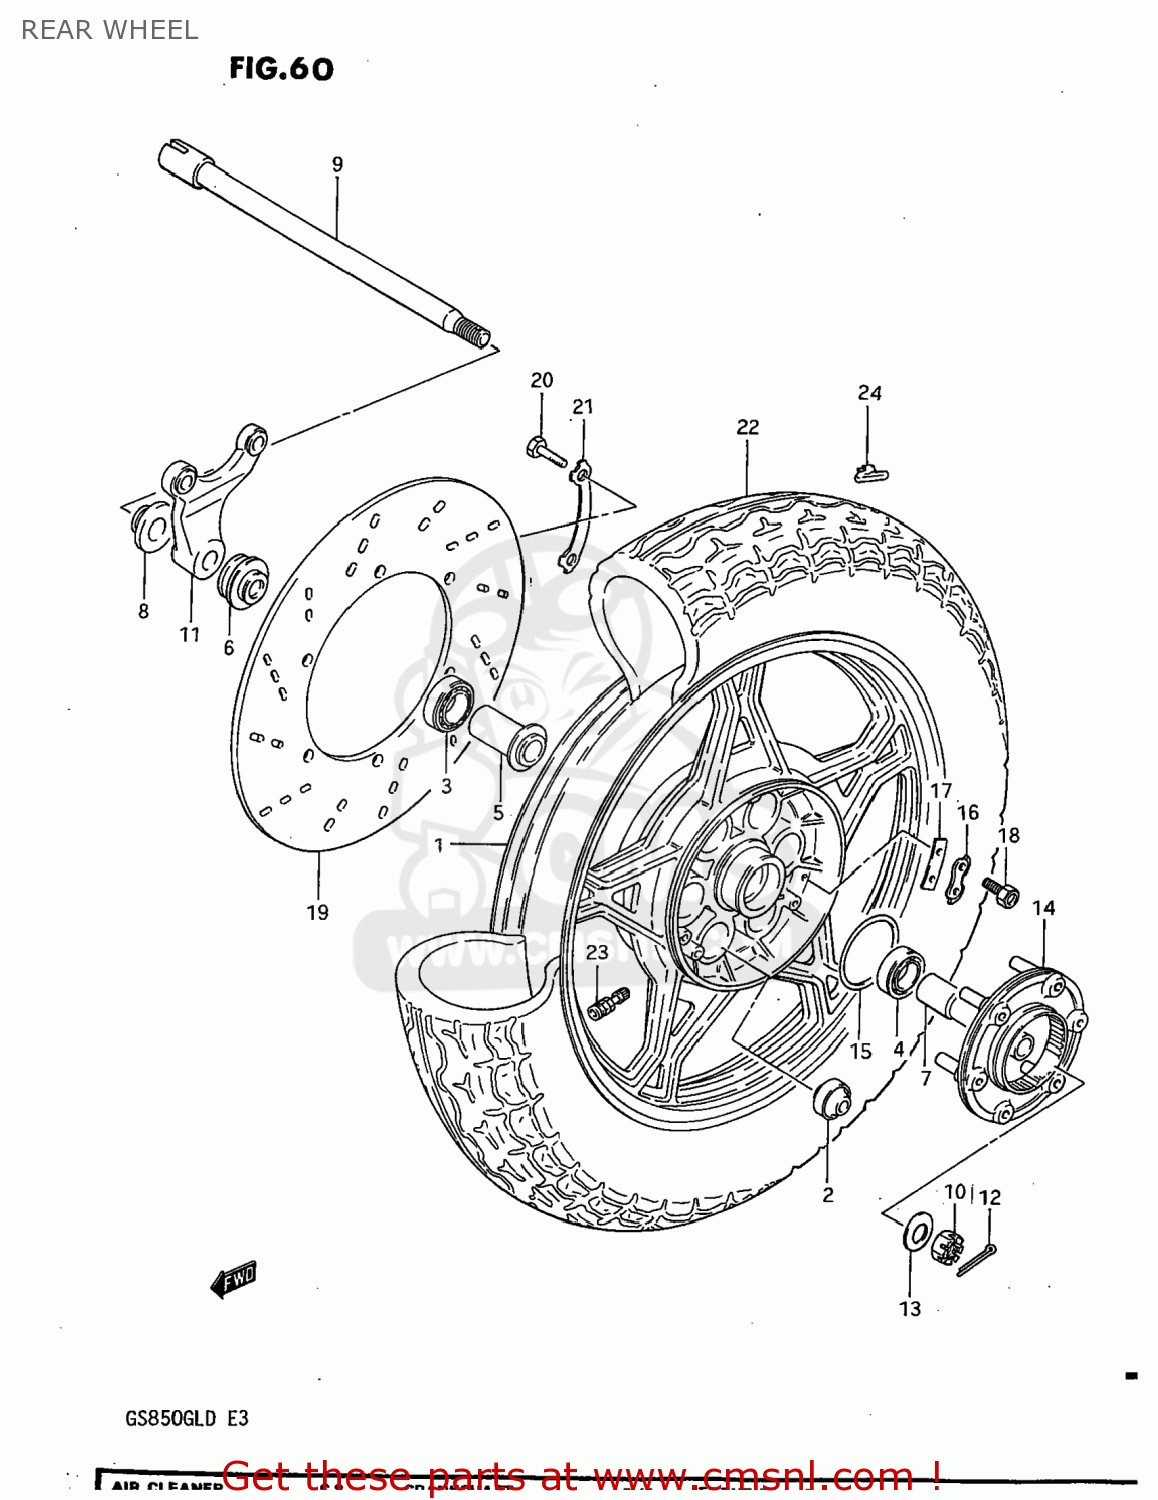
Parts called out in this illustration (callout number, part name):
1	CASTING WHEEL,REAR
2	BUSH
3	BEARING
4	BEARING
5	SPACER,REAR HUB BEARING
6	SPACER,REAR AXLE
7	SPACER,REAR AXLE,LEFT
8	SPACER,REAR AXLE,RIGHT
9	AXLE,REAR
10	NUT
11	BRACKET,RR,CALIPER
12	PIN,COTTER
13	WASHER (17.5X36X3.2)
14	JOINT ASSEMBLY,REAR HUB DRUM
15	O RING(D:2.1,ID:65)
16	WASHER
17	WASHER,THRUST(T:1.6)
18	BOLT(6X16)
19	DISC,RR BRAKE
20	BOLT(8X25)
21	WASHER
22	TIRE
23	VALVE ASSEMBLY,WHEEL RIM,J
24	BALANCER,WHEEL
